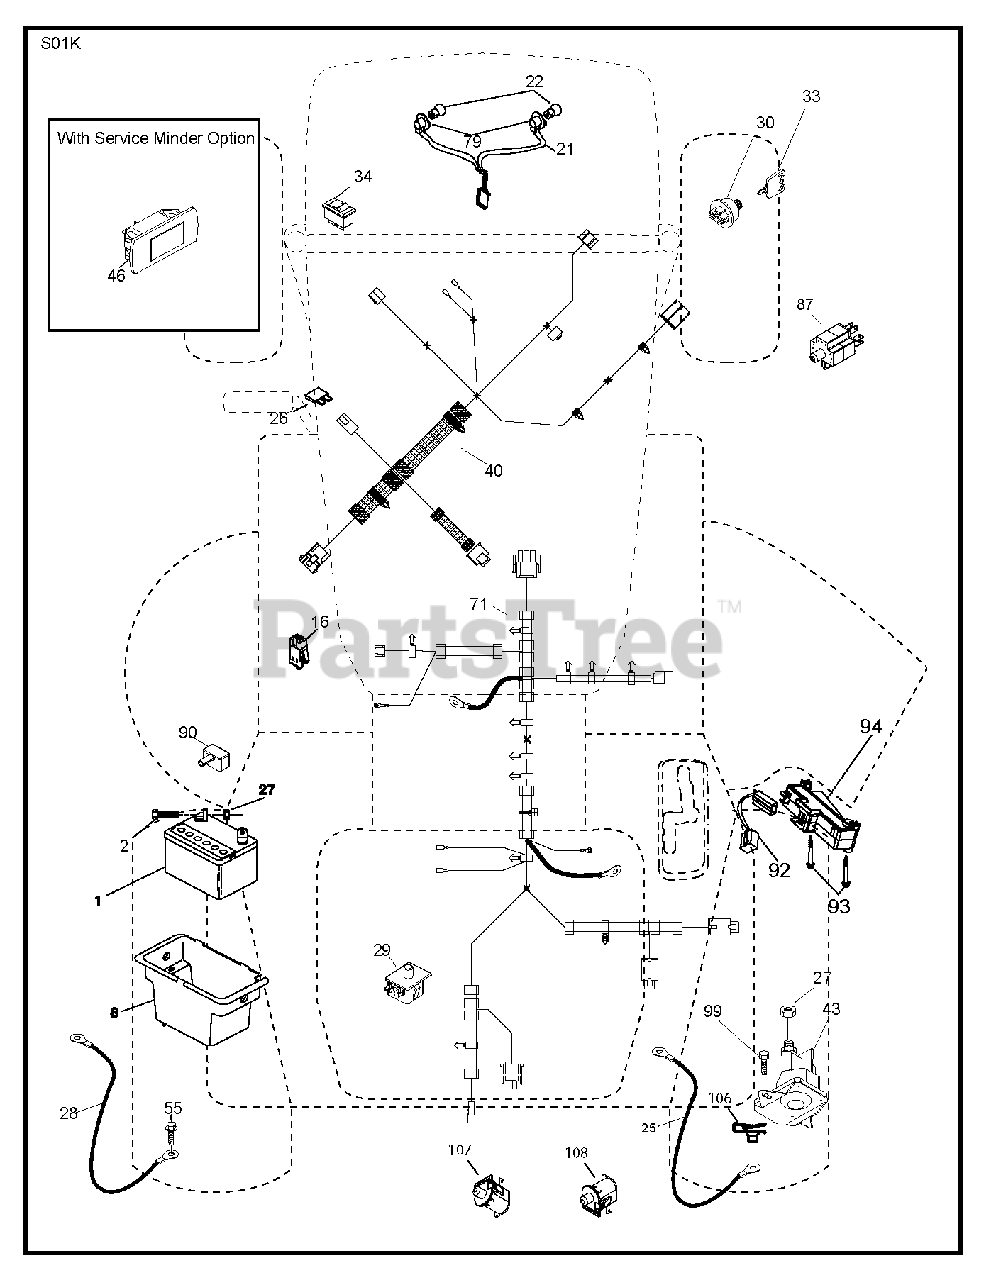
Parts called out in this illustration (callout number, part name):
1	REPL BY 532 12 38-99
2	BOLT.HEX.1/4.X.3/4.DICHROMATE
8	BOX.BATTERY.LT/SRD
16	SWITCH INTERLOOK PUSH-IN
21	HARNESS.LIGHT W/4152J BULBS
25	CABLE.BATTERY.20.RED.8 AWG
26	FUSE 20AMP
27	NUT
28	CABLE.GROUND.REAR.BATTERY.8G
29	SWITCH.SEAT.DELTA.OPC.
30	SWITCH.IGN.DELTA.W.LGH.ROS
33	KEY.CHAIN.BLISTER.PACK.GEN.INT
40	RP HARNESS.ELECTRICAL.DASH.SRD
43	SOLENOID.W/BRASS.PLUNGER
55	SCREW 5/16"
71	RP HARNESS.ELEC.CHASSIS.SRD
79	BULB HOLDER ASM.
87	RP SWITCH.RAILMOUNT.NO-NC-NC
90	COVER.TERMINAL.BATTERY
92	HARNESS.PIGTAIL.CONSLE
93	SCREW.PLASTITE
94	MODULE.REVERSE.ROS
99	SCREW HEXWSHR 1/4-20X3/4
106	1/4-20 U NUT
107	SWITCH.SNAPMOUNT.NO.#2
108	SWITCH.SNAPMOUNT.NC
